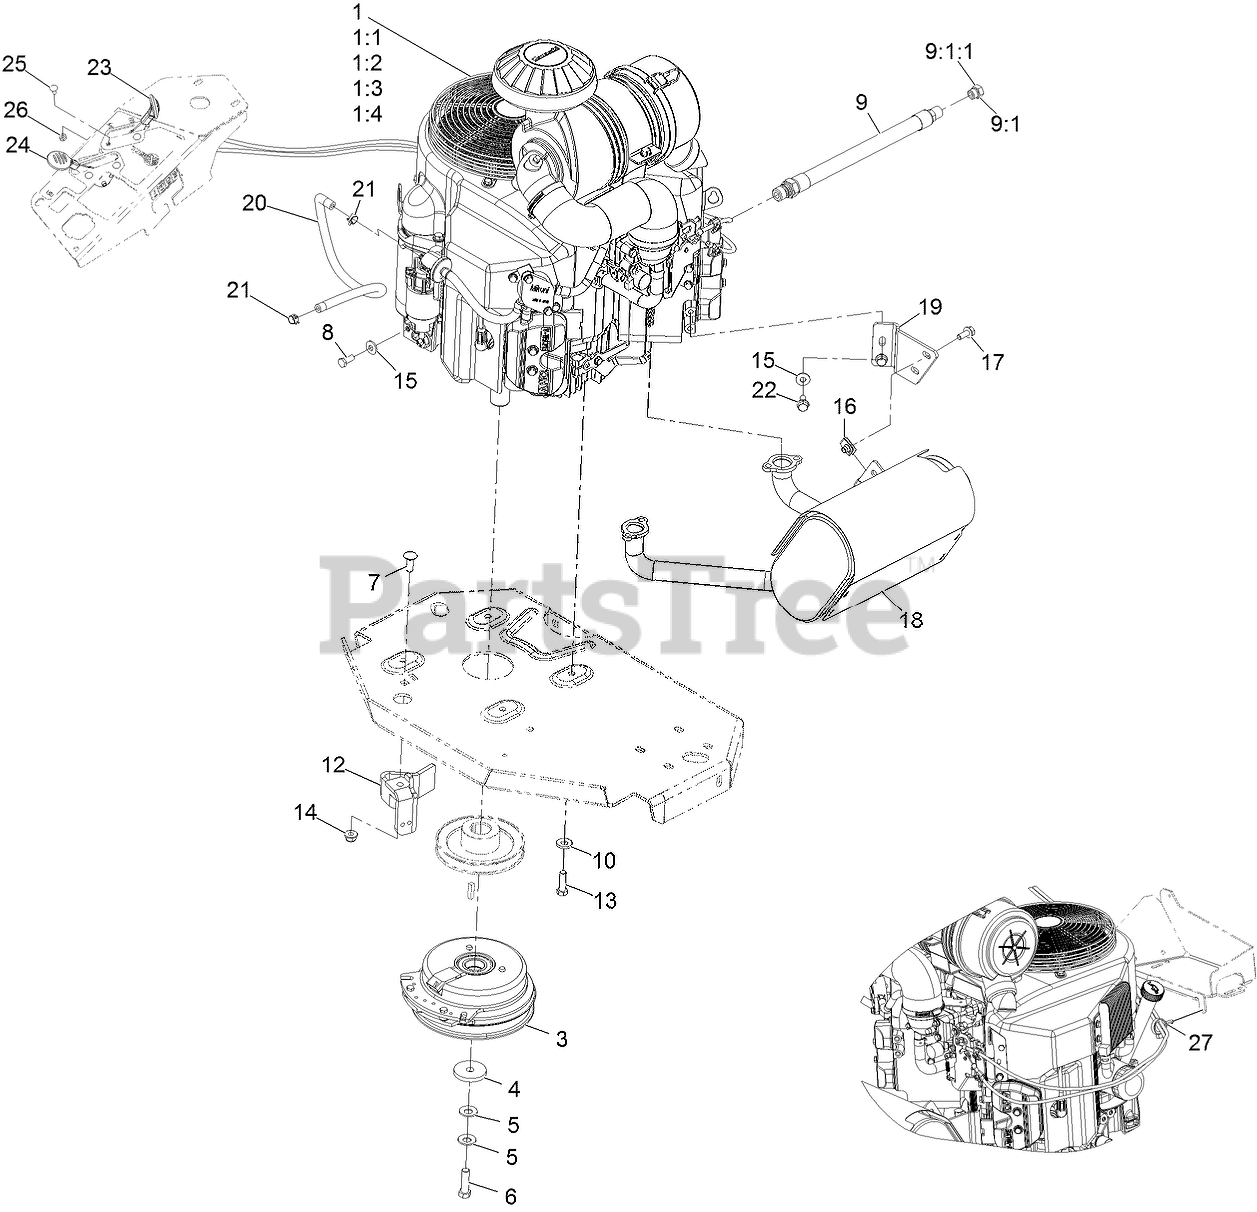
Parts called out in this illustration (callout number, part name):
1:1	Kawasaki 49065-2078 Engine Oil Filter
1:2	Kawasaki 49019-0031 Fuel Filter
1:3	Kawasaki 11013-7039 Safety Filter
1:4	Kawasaki 11013-7038 Air Filter
3	CLUTCH KIT
4	WASHER-CLUTCH
5	WASHER-SPRING
6	SCREW-HH 7/16-20 X 1 1/2 W/LOCTITE
7	SCREW-CARR
8	SCREW-HH
9	ENGINE OIL DRAIN HOSE ASM
9:1	PLUG-HH
9:1:1	O-RING
10	WASHER-BELLEVILLE
12	CLUTCH-ANCHOR
13	SCREW-HH
14	NUT-HF, NI
15	WASHER-SPRING
17	SCREW-HHF
18	MUFFLER
19	BRACKET-MUFFLER
20	HOSE-FUEL
21	CLAMP-HOSE
22	SCREW-HHF
23	ASM, CHOKE CABLE
24	ASM,THROTTLE CABLE
25	BOLT-CARR
26	NUT-LOCK, NI
27	CLAMP-HOSE
